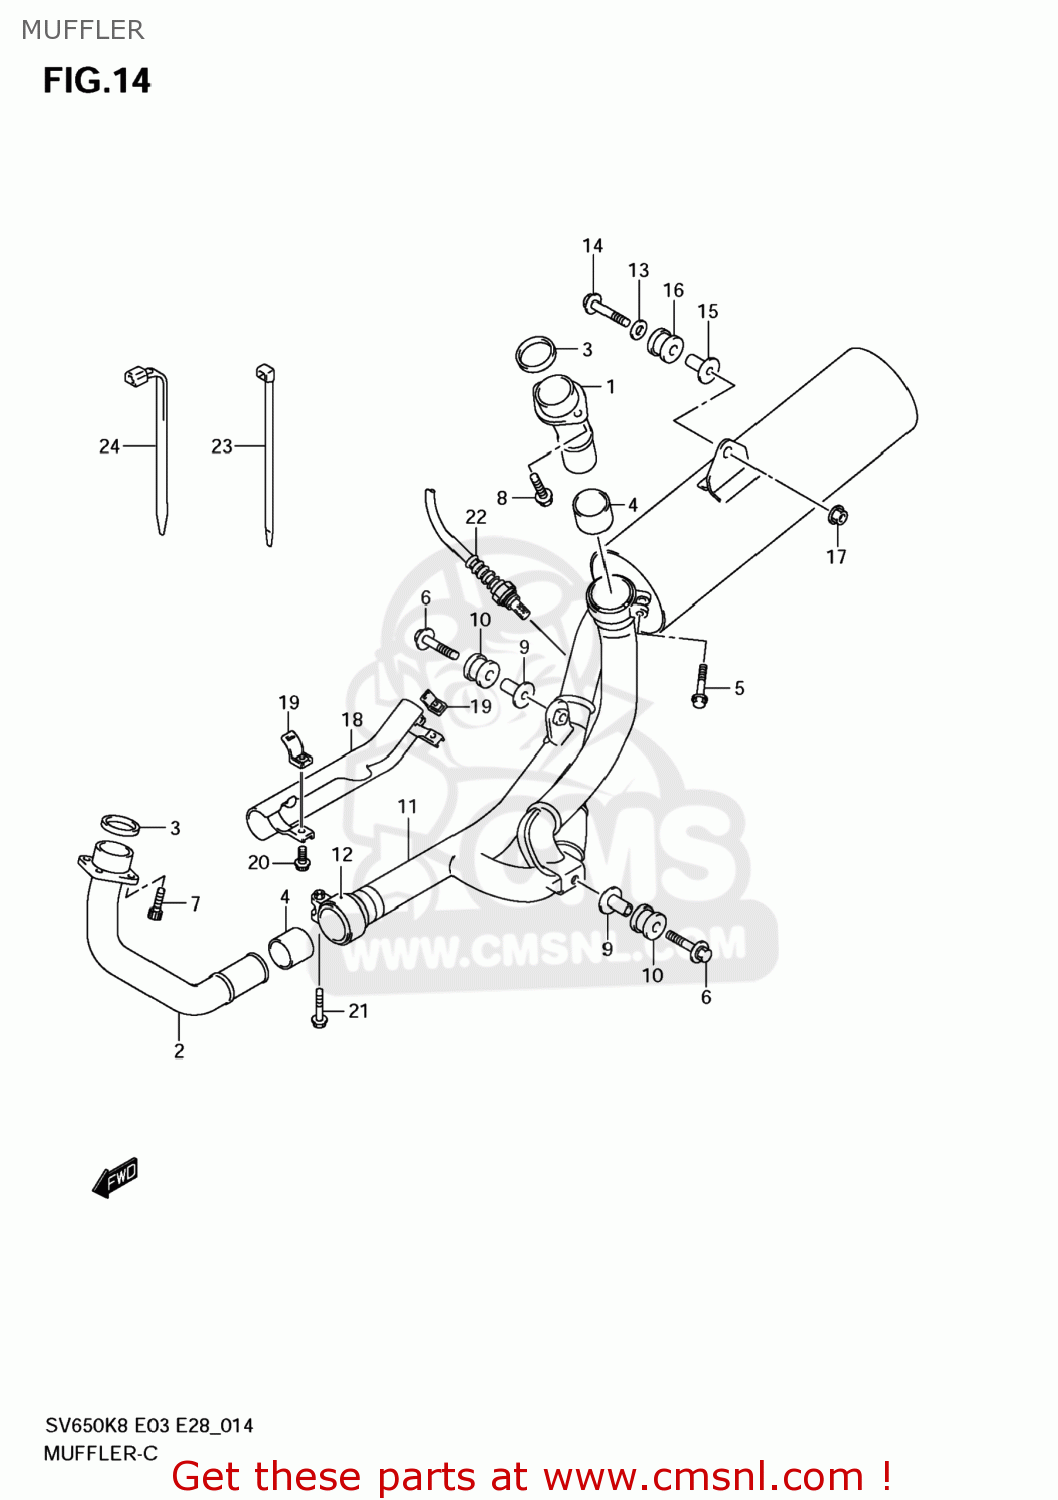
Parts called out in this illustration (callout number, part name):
1	PIPE,EXHAUST RR
2	PIPE,EXHAUST FR
3	GASKET,EXHAUST PIPE (NAS)
4	CONNECTOR,MUFFLER
5	BOLT
6	BOLT 8X45
7	BOLT(8X25)
8	BOLT
9	SPACER(8.6X12X24.2)
10	CUSHION
11	MUFFLER
12	CLAMP,MUFFLER CONNECTOR
13	WASHER(8.5X28X1.5)
14	BOLT(8X45)
15	SPACER(8.6X12X24.2)
16	CUSHION
17	NUT
18	COVER,EXHAUST TT
19	CLAMP,EXHAUST COVER
20	BOLT(6X20)
21	BOLT(8X35)
22	SENSOR,OXYGEN
23	CLAMP(L:100)
24	CLAMP(L:125)
